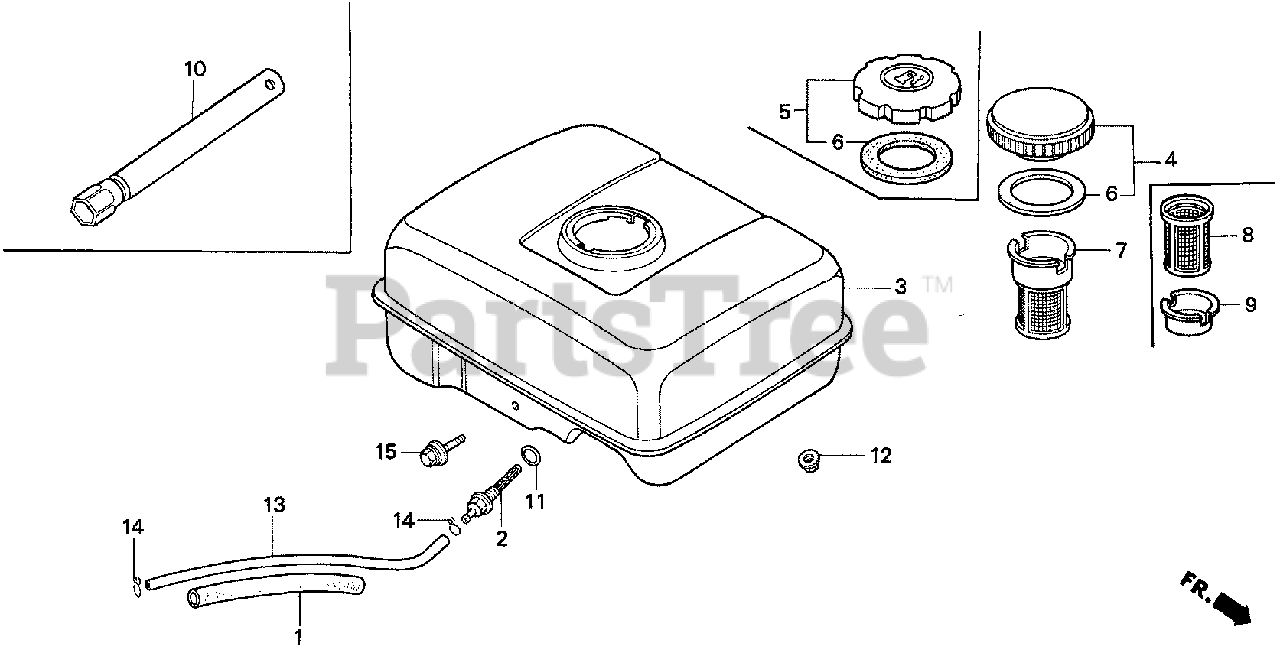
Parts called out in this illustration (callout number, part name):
1	RUBBER, SUPPORTER (107MM)
2	JOINT, FUEL TANK
3	TANK, FUEL *NH31* (MCKINLEY WHITE)
4	CAP, FUEL FILLER
5	CAP, FUEL FILLER
6	GASKET, FUEL FILLER CAP
7	FILTER, FUEL
8	FILTER, FUEL
9	HOLDER, FUEL FILTER
10	WRENCH, SPARK PLUG
11	O-RING (13.5X1.5) (ARAI)
12	NUT, FLANGE (6MM)
13	BULK HOSE, FUEL (4.5X3000) (4.5X140)
14	CLIP, TUBE (B8)
15	BOLT, FLANGE (6X25)
